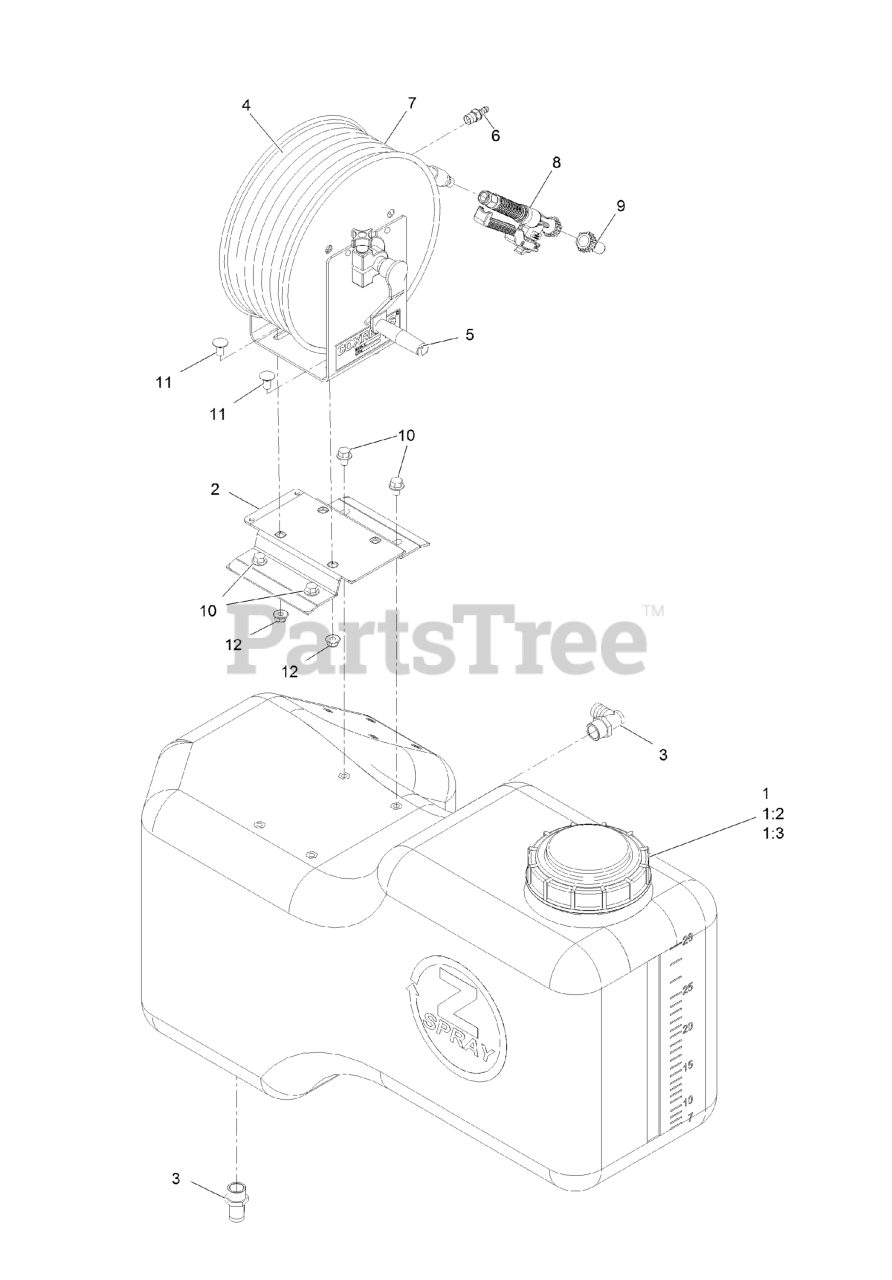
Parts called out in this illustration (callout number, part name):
1	ASM-Tank, Lt
1:2	CAP-TANK, SPRAY
1:3	FITTING-BULKHEAD
2	MOUNT-REEL, HOSE
3	FITTING-ELBOW, 90
4	REEL-HOSE
5	Crank-Reel
6	FITTING,MALE
7	HOSE-SPRAY, 75'
8	GUN-SPRAY, SPOT
9	TIP-SPRAY, #12 SPOT
10	Screw-HHF
11	SCREW-CARRIAGE
12	Nut-Hex Flange
